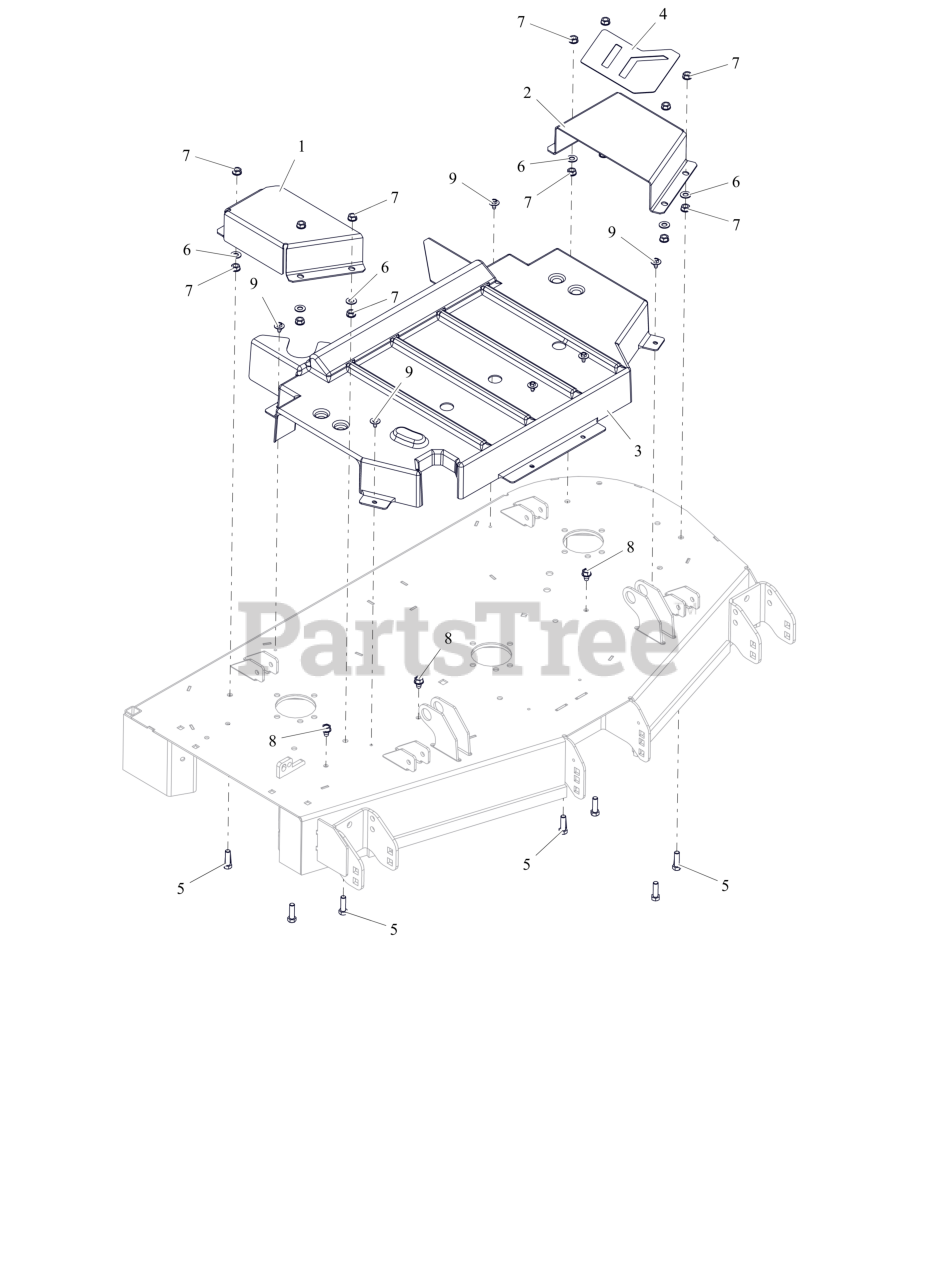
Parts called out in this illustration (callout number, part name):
1	GUARD, BELT 48" RIGHT CE (ORANGE)
2	GUARD, BELT 48" LEFT CE (ORANGE)
3	GUARD, CENTER DECK SPINDLE CE
4	GRIP TAPE 48 BELT COVER
5	BLT, HEX .38-16X1.25 G5 ZCC
6	WSHR,FLT .406X.812X.065 ZCC
7	NUT, SPNLK-FLG .38-16 G5 ZCC
8	SCR,TAP .375-16X.50 HWH TR ZCC
9	SCR, TAP .25-20X.50 LG HWH ZCC
